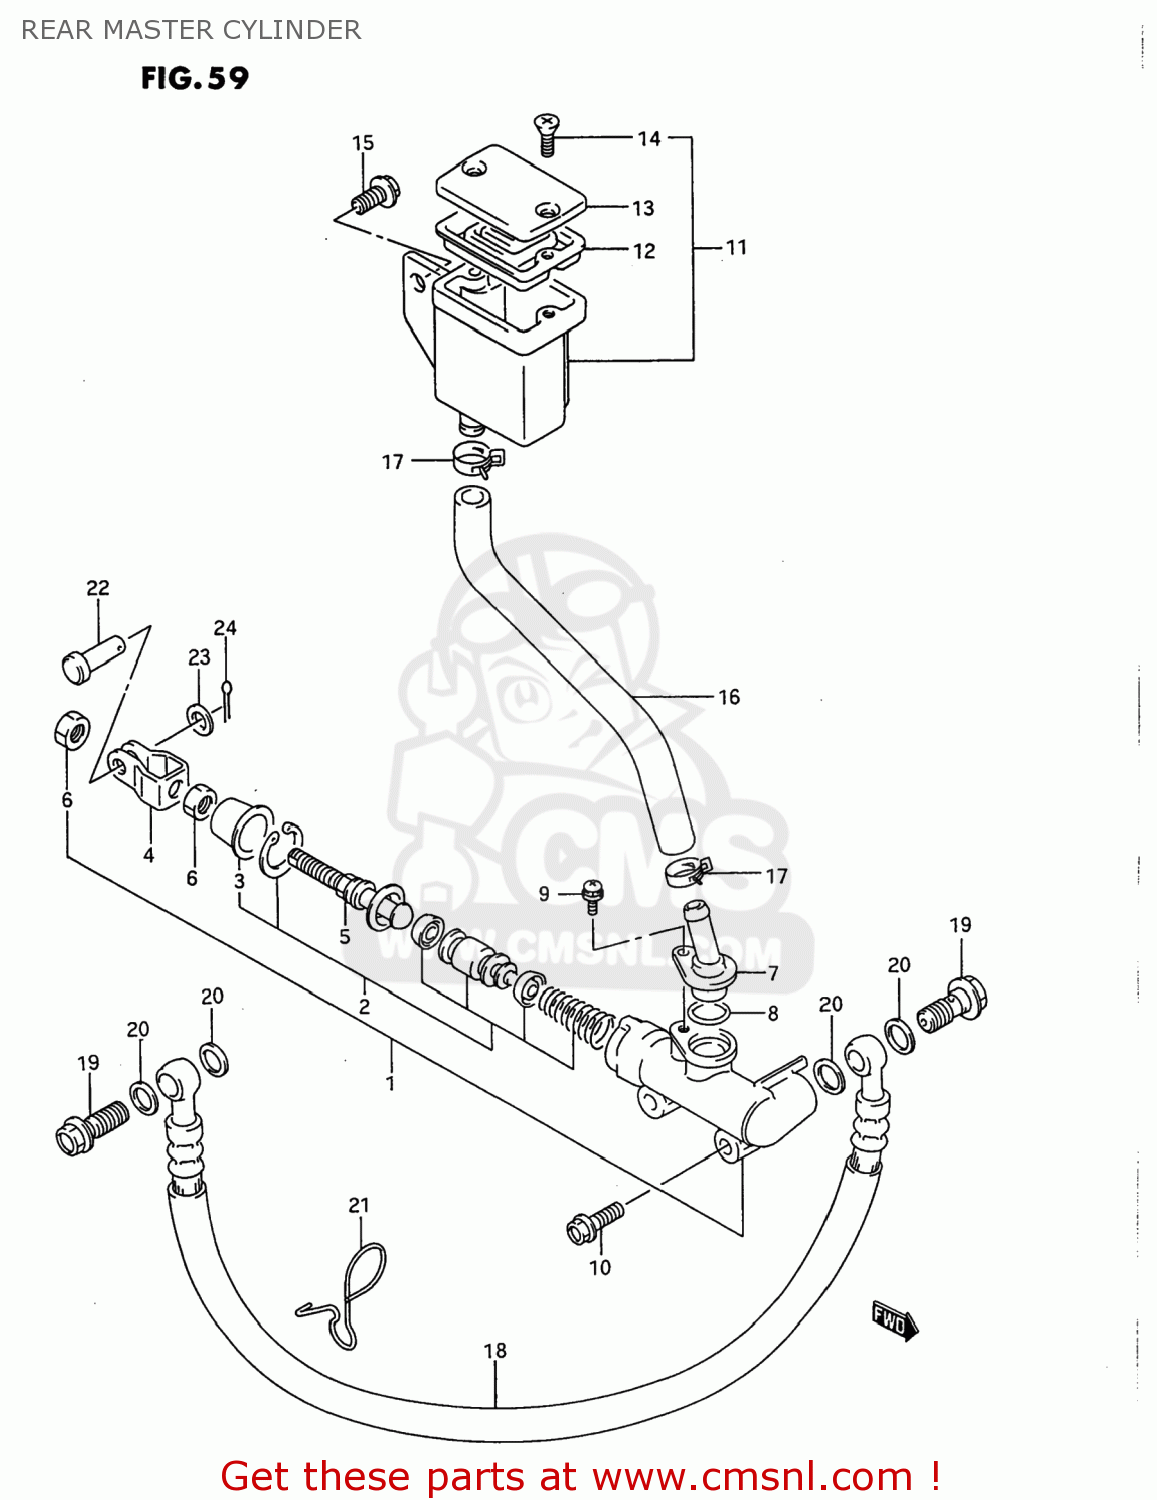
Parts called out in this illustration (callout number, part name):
1	CYLINDER ASSEMBLY,REAR MASTER
2	PISTON/CUP SET
3	BOOT
4	YOKE
5	ROD,PUSH
6	NUT
7	CONNECTOR
8	O RING
9	SCREW
10	BOLT,OIL FILLE
11	TANK ASSY,RESERVOIR
12	DIAPHRAGM
13	CAP
14	SCREW
15	BOLT
16	HOSE,RESERVOIR TANK
17	CLIP
18	HOSE,RR BRAKE
19	BOLT UNION
20	WASHER(10X15X1.5)
21	GUIDE,BRAKE HOSE
22	PIN
23	WASHER
24	PIN
